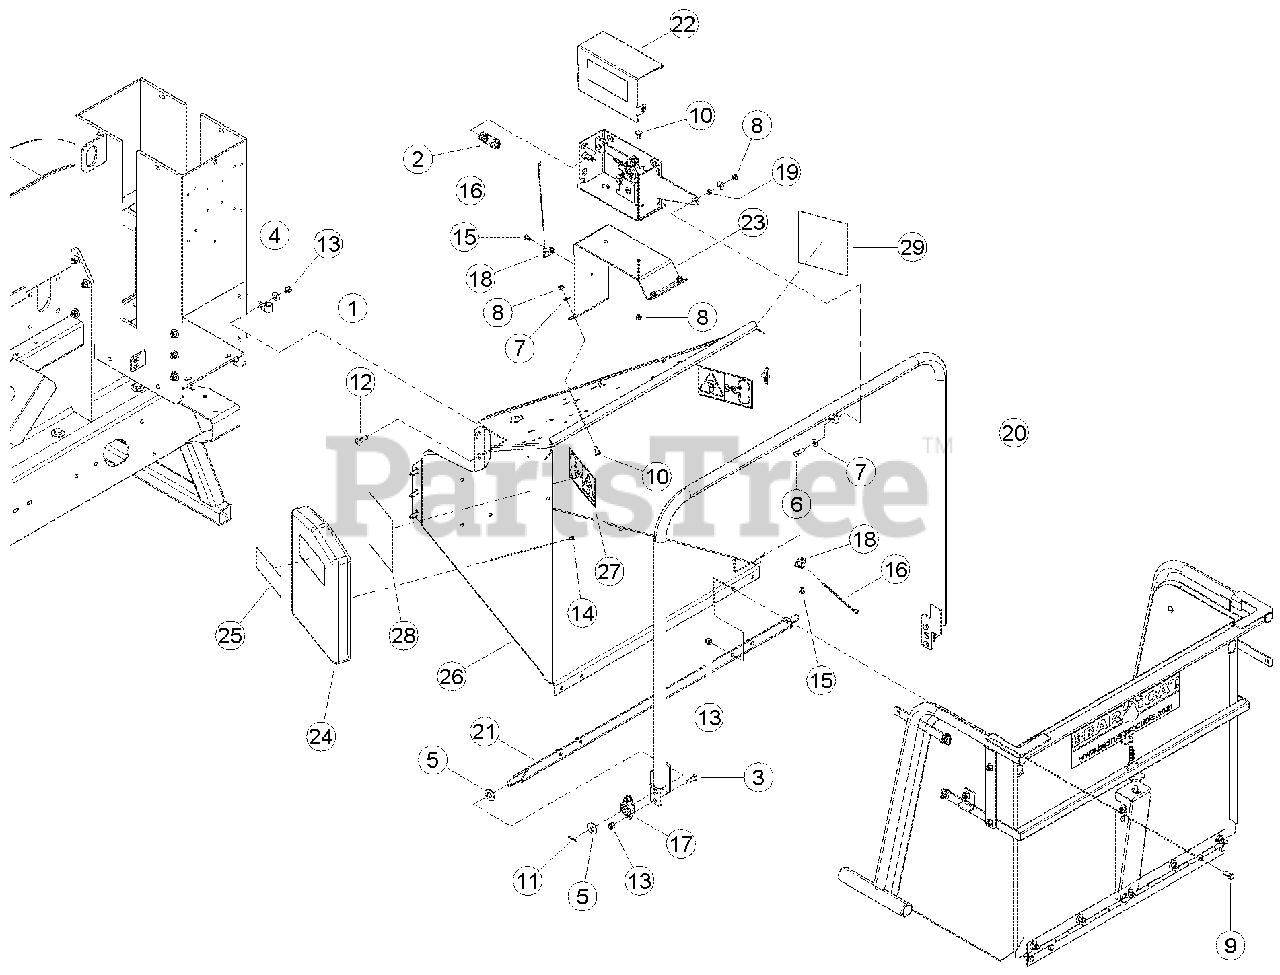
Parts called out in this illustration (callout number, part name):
1	CLAMP, 9/16" COATED
2	SWITCH, MOMENTARY IP65. (FOR SERVICE ORDER KIT #77536-00)
3	BOLT, 3/8 X 1 HEX HD GR5 ZP
4	WASHER, 3/8 FLAT ZP
5	WASHER, 5/8 SAE FLAT ZP
6	BOLT, 5/16 X 1 HEX HD GR5 NC ZP
7	WASHER, 5/16 FLAT ZP
8	NUT, 5/16 NE NYLOCK ZP
9	BOLT, 3/8 X 1-1/4 HEX HD GR5 ZP
10	BOLT, 5/16 X 3/4 CRG GR5 NC ZP
11	PIN, 1/8 X 1.00 ZP COTTER
12	BOLT, 3/8 X 1-1/4 CRG GR5 NC ZP
13	NUT, 3/8 NE NYLOCK ZP
14	RIVET, AL BLIND 1/4 X 1/2 DOME HEAD
15	RIVET, AL BLIND 1/4 X 3/4 DOME HEAD
16	STRAP, 11 IN. BLACK TIE
17	BEARING, SIDE FLANGE MOUNT 5/8"
18	CLAMP, CABLE MOUNT
19	SPACER, IDLER PIVOT
20	WELDMENT, CONTROL ARM
21	WELDMENT, CONTROL PIVOT
22	ASSEMBLY, SWITCH BOX. (REPLACED AND SUPERSEDED. FOR SERVICE ORDER KIT #77536-00, CONTROL SWITCHES.
22	ASSEMBLY, SWITCH BOX. FOR SERVICE, ORDER 77536-00, KIT, CONTROL SWITCHES.
23	MOUNT, SWITCH BOX
24	ASSEMBLY, MANUAL CONTAINER SERVICE PART
25	DECAL, MUTILINGUAL MANUAL
26	ASSEMBLY, BIG CHIPPER CHUTE SERVICE PART
27	DECAL, BLADE DANGER ISO
28	DECAL, FEED POSITION
29	DECAL, FEED POSITION
